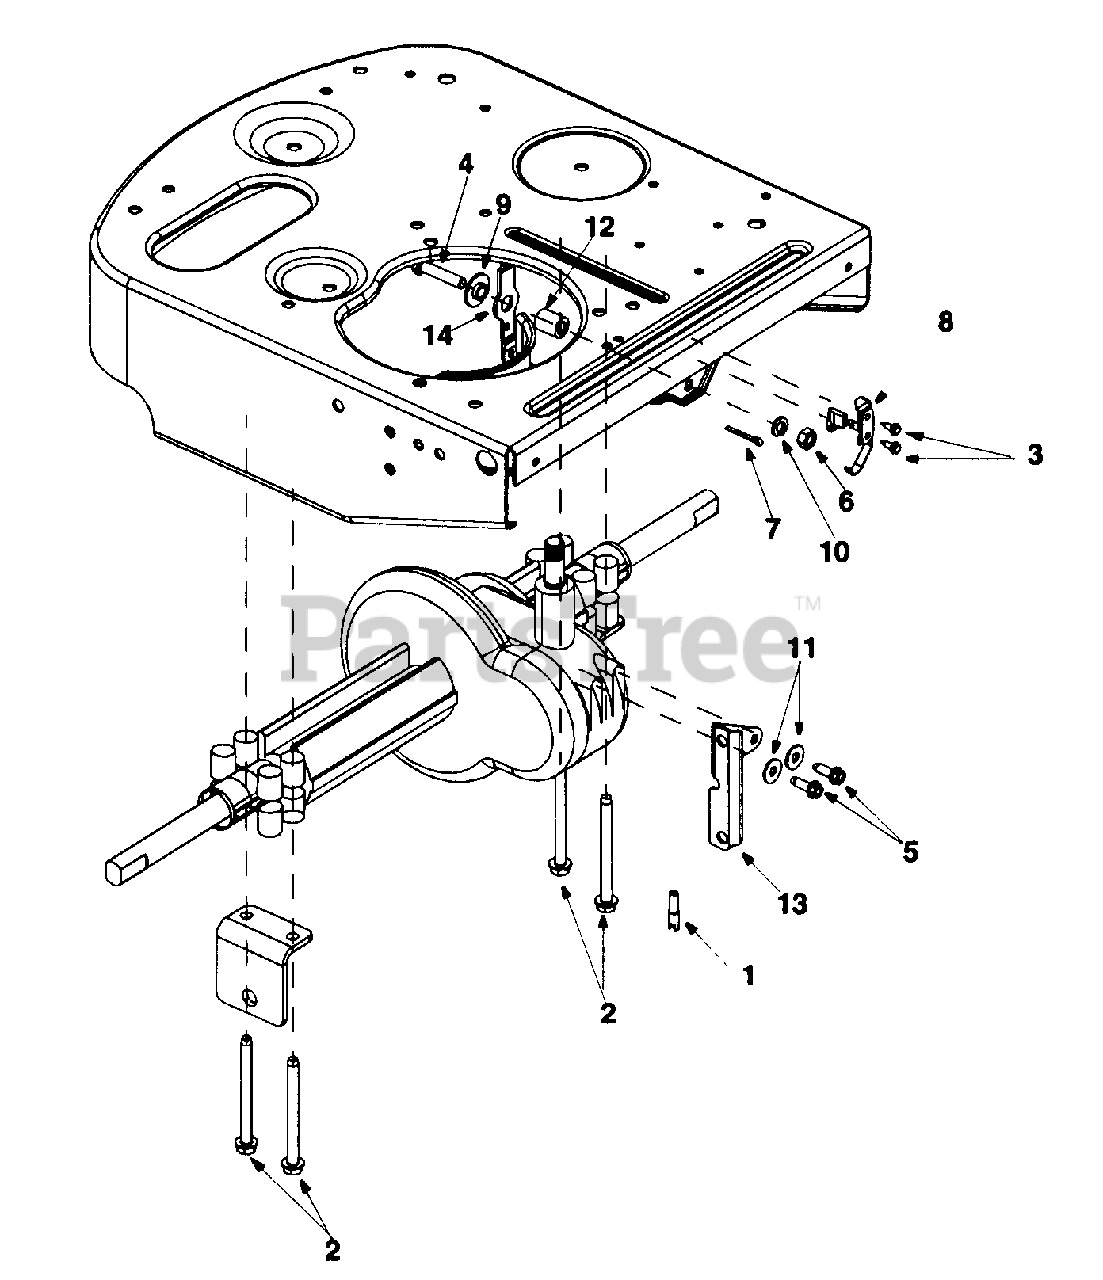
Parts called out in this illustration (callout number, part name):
1	Harness Assembly Adapter
2	Hex TT Screw 5/16-18 x 3.50
3	Hex Washer Head Self-Tap.Screw
4	Hex Screw 5/16-18 x 1.5 Gr. 5
5	Thd. Forming Scr. 1/4-20 x .75
6	Hex Nut 5/16-18
7	Cotter Pin
8	Insulator Nut Plate
9	Shoulder Bushing
10	Lock Washer 5/16
11	Flat Washer .28 I.D. x .74 O.D. x .083
12	Spacer
13	Transaxle Bracket
14	Shift Lever
